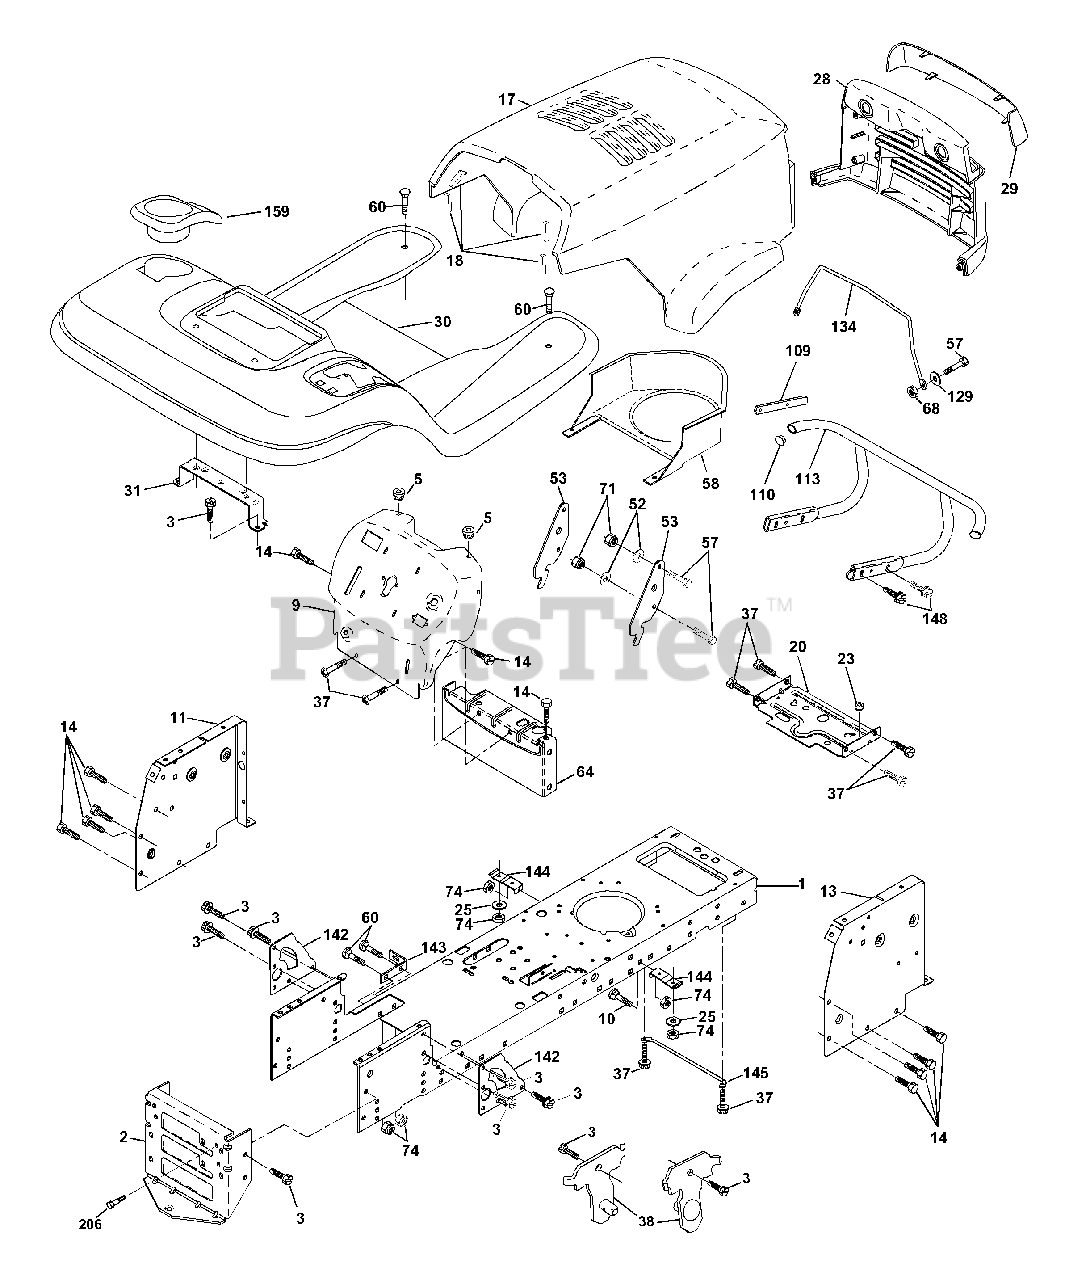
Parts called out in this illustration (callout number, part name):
1	Chassis stamping
2	Drawbar, 12 Ga.
3	Screw 3/8-16x3/4
5	Bumper Hood/Dash
9	Dash Slkscr
10	Bolt Carriage 3/8-16 x 1
11	Panel Dash Lh
13	Panel Dash Rh
14	Screw Thdrol 3/8-16x1/2 Ty-tt
17	Hood LT/PL Husqvarna
18	Bumper Hood
20	Plate Mtg Battery Fuel Tank Fr
25	Washer 13/32 X 13/16 X 12 Ga
28	Grille LT/PL Husqvarna
29	Lens LT/PL Husqvarna
30	Fender Footrest STLT Pnt
31	Bracket Support Fender
37	Screw Thdrol 6/16-18 x 1/2 TYT
38	Bracket Asm Pivot Mower Rear
52	Washer 9/32 x 7/8 x 16 Ga.
53	Bracket Pnt. Pick off LT/PL Husqvarna
57	Bolt Hex 1/4-20 x 3/4
58	Air Duct Engine P/L
60	Bolt Rdhd Sqnk 3/8-16unc x 3/4
64	Dash Lower STLT
68	Nut Keps Hex 1/4-20unc
71	Nut Crown Lock 1/4-20 Unc
74	Nut Crownlock 3/8-16 UNC
109	Bracket Extension Bumper
110	Plug Plastic
113	Bumper Asm.
129	Washer 9/32 x 5/8 x 16 Ga.
134	Rod Support Hood LT/PL Husq.
142	Plate Reinforcement STLT
143	Bracket Swaybar Chassis
144	Bracket Pnt Footrest STLT
145	Rod Pivot Chassis/Hood
148	Screw 3/8-16 x 1-1/4
159	Cupholder Stlt Grey
206	Bolt Shoulder 5/16-18 TT
